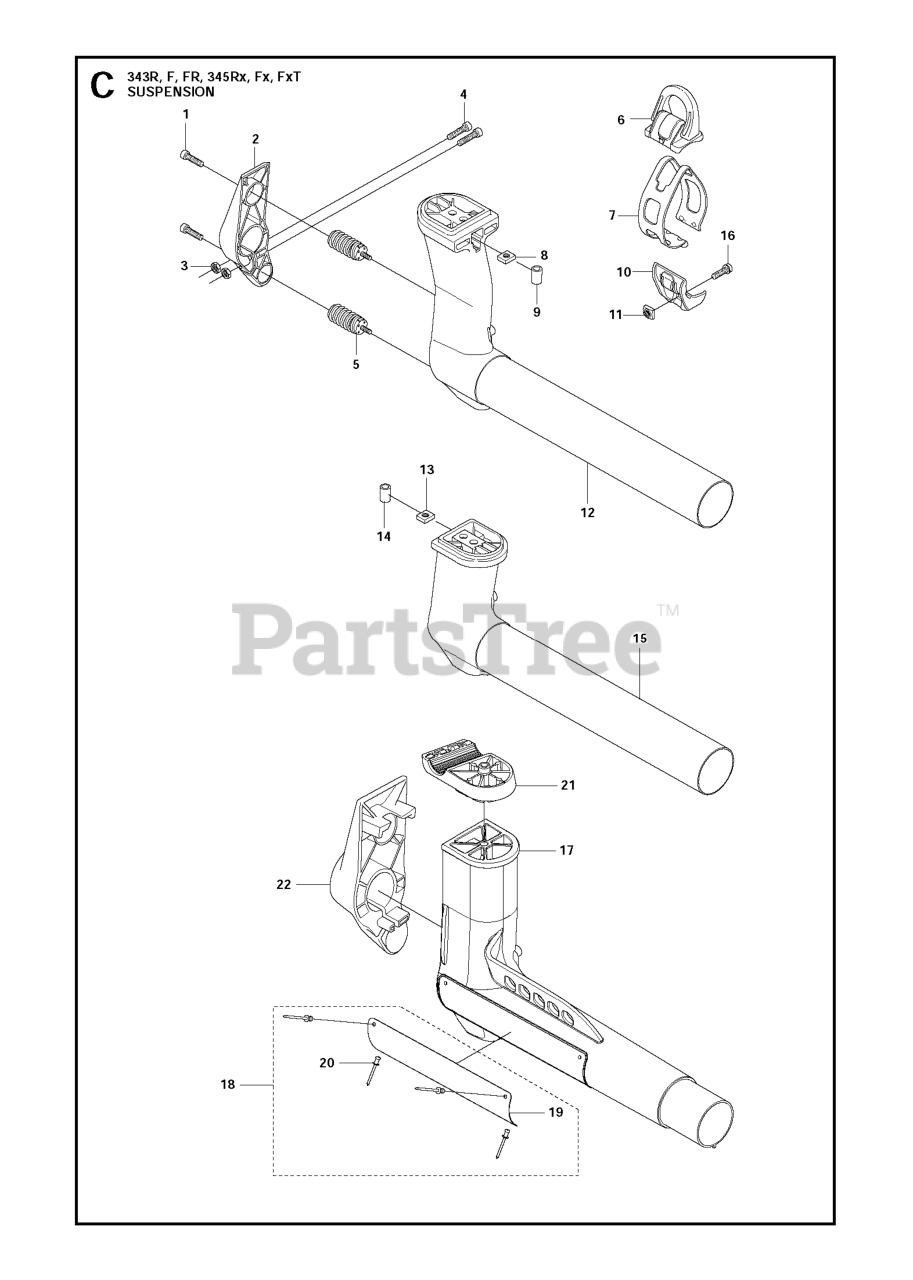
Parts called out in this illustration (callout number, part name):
2	HOLDER
6	LOOP
10	BRACKET, LOWER HANGER
11	SQUARE NUT M5
12	SUPPORT
15	SUPPORT
17	SUSPENSION
18	WEAR PROTECTION
19	WEAR PROTECTION
20	BLIND RIVET
21	HANDLEBAR BRACKET
22	HOLDER ANTIVIBRATION
